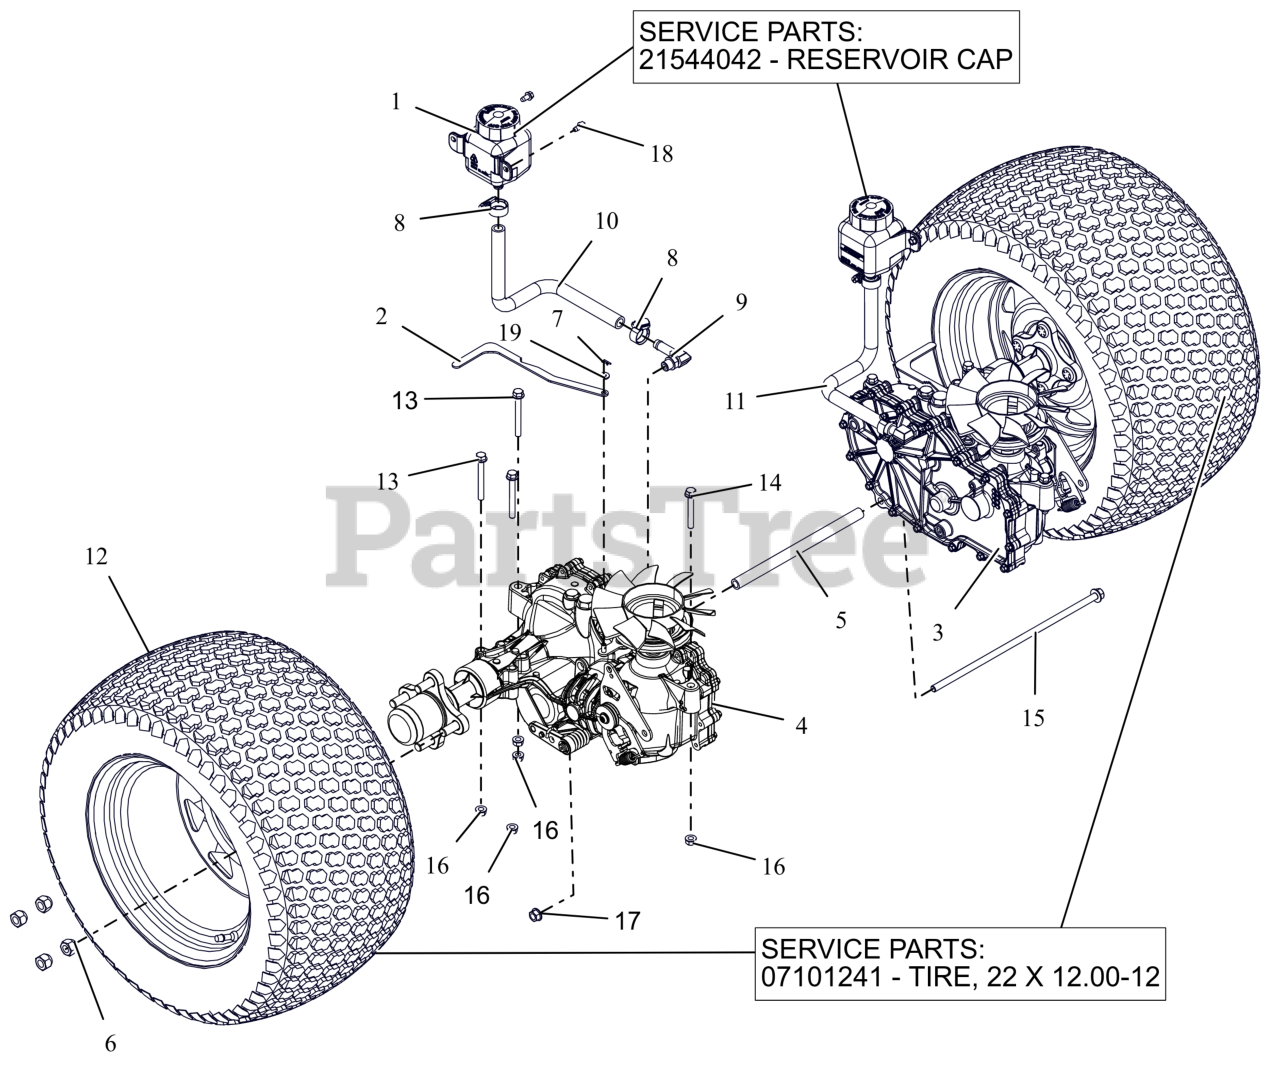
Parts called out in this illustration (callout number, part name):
1	TANK, EXPANSION
1	CAP, HYDRO RESERVOIR REPLAC.
2	BRKT, VALVE DUMP
3	TRANSAXLE, ZT3200 LH
4	TRANSAXLE, RH ZT3200
5	SPCR,TRANS. .406IDX.63ODX9.95L
6	NUT, WHEEL .50-20 ZCC
7	PIN, HAIR #225 .072X1.09
8	CLAMP,.88 DIA. HOSE
9	FITTING, HYD (90 DEG)
10	HOSE, FORMED EXPANSION -HD RH
11	HOSE, FORMED EXPANSION -HD LH
12	ASM, WHL/TIRE 22X12.00-12 K500
12	TIRE, 22X12.00-12
13	BLT,HEX-FLG .31-18X2.75 G5 ZCC
14	BLT,HEX-FLG .31-18X2.25 G5 ZCC
15	BLT,HEX-FLG .38-16X13 G5 ZCC
16	NUT,LK-CTR-FLG .31-18 GF ZCC
17	NUT-LK-CTR-FLG .375-16 GF ZCC
18	SCR-TAP .25-20X.50 HWH ZCC
19	WSHR,FLT .281X.625X.065 ZCC
